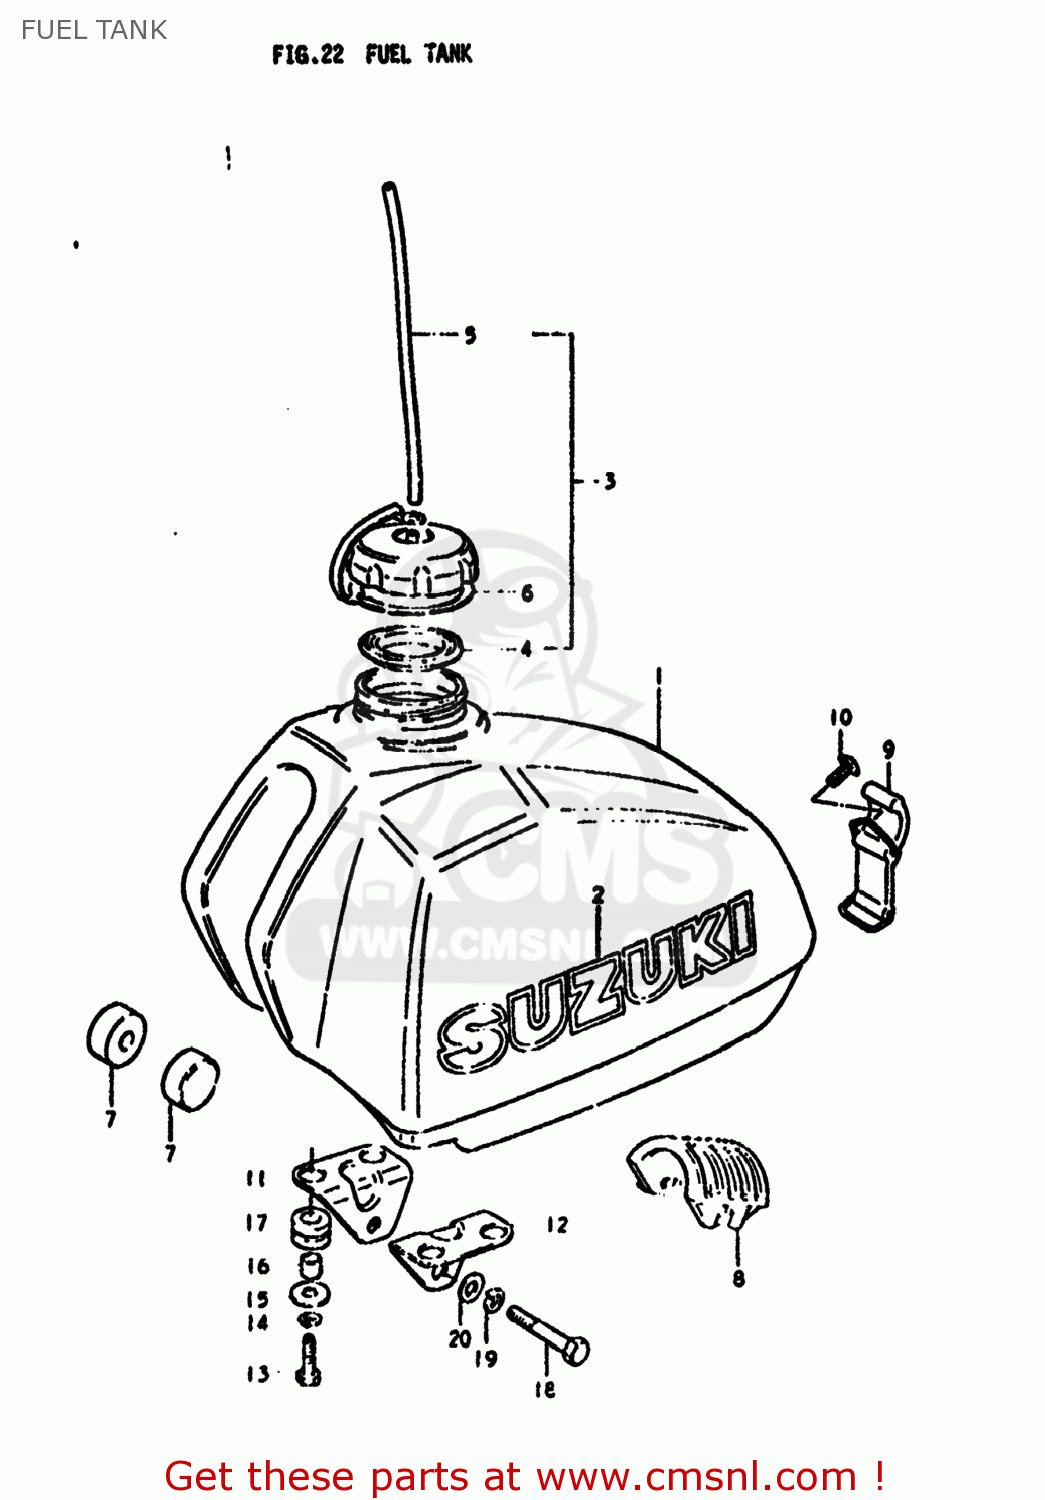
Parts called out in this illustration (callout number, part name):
1	TANK ASSEMBLY,FUEL
2	EMBLEM(BLACK)
3	CAP ASSY,FUEL TANK
4	GASKET,FUEL TANK CAP (NAS)
5	HOSE
6	BAND,FUEL TANK CAP
7	CUSHION
8	CUSHION,FUEL TANK
9	BAND
10	SCREW(6X18)
11	BRACKET,FUEL TANK
12	BRACKET,FUEL TANK
13	BOLT
14	LOCK WASHER
15	WASHER (6.5X24X1.6)
16	SPACER(6.8X12X11)
17	CUSHION
18	BOLT
19	LOCK WASHER
20	WASHER
